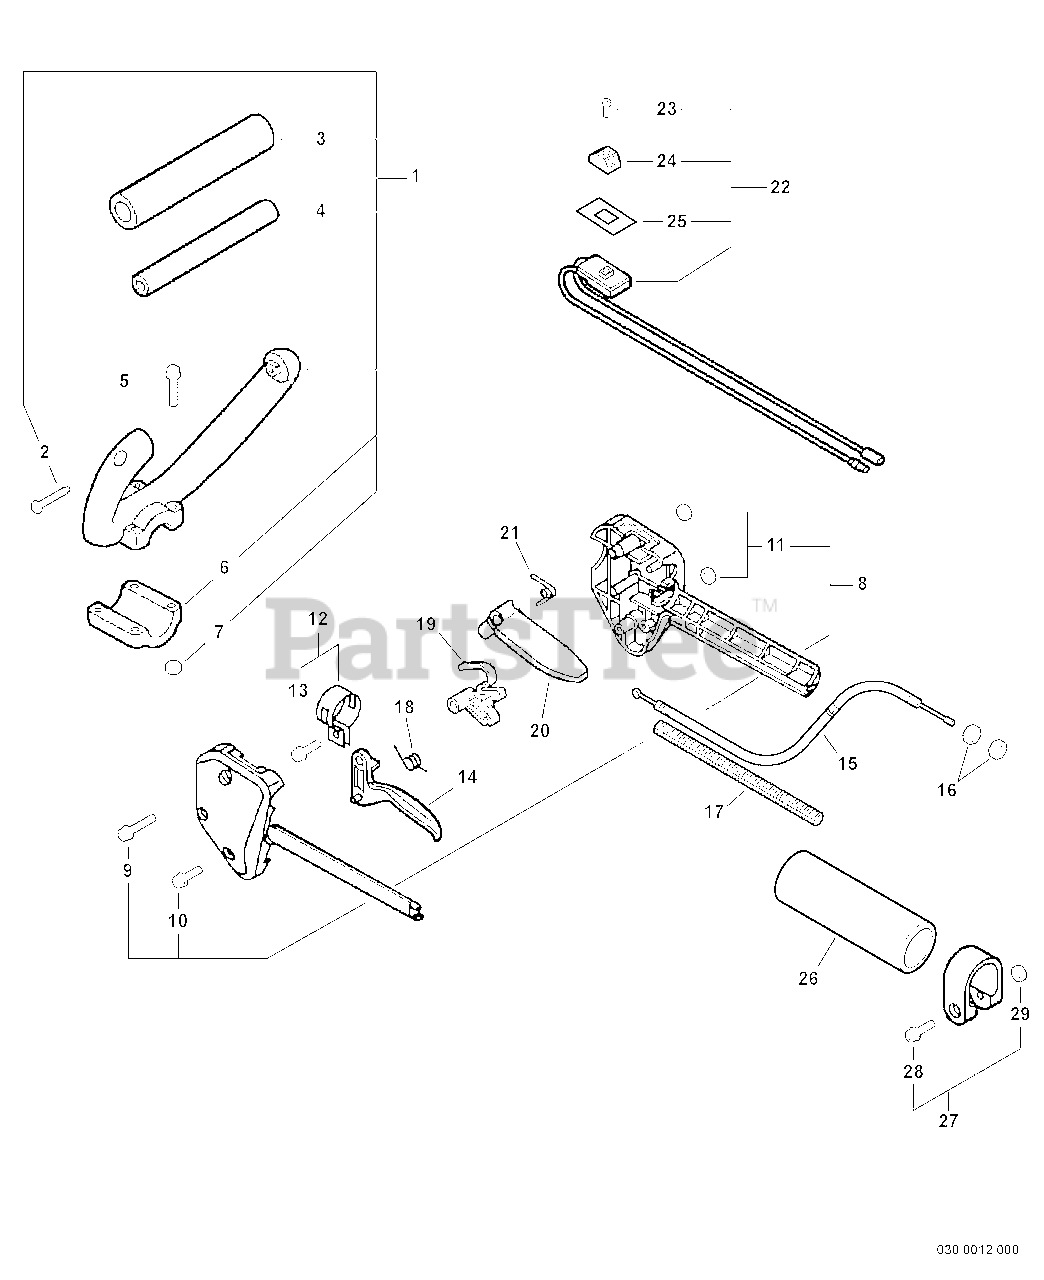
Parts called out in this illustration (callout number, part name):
1	LOOP HANDLE ASSY
2	SCREW 5×30
3	GRIP, HANDLE
5	SCREW 5×35
6	BRACKET, HANDLE - LOWER
7	NUT M5
8	HANDLE KIT, CONTROL
9	SCREW 5×35
10	SCREW 5×25
11	NUT M5
12	CLAMP KIT
13	SCREW 5×14
14	TRIGGER, THROTTLE
15	CABLE, THROTTLE
17	TUBE, FLEXIBLE
18	SPRING, TORSION
19	LOCKOUT, THROTTLE
20	LEVER, THROTTLE LOCKOUT
21	SPRING, TORSION
22	SWITCH, ON-OFF
23	SCREW 3×10
24	KNOB, SWITCH - ORANGE
25	LABEL, SWITCH
26	GRIP, HANDLE
27	CLAMP KIT
28	SCREW 5×28
29	NUT M5
